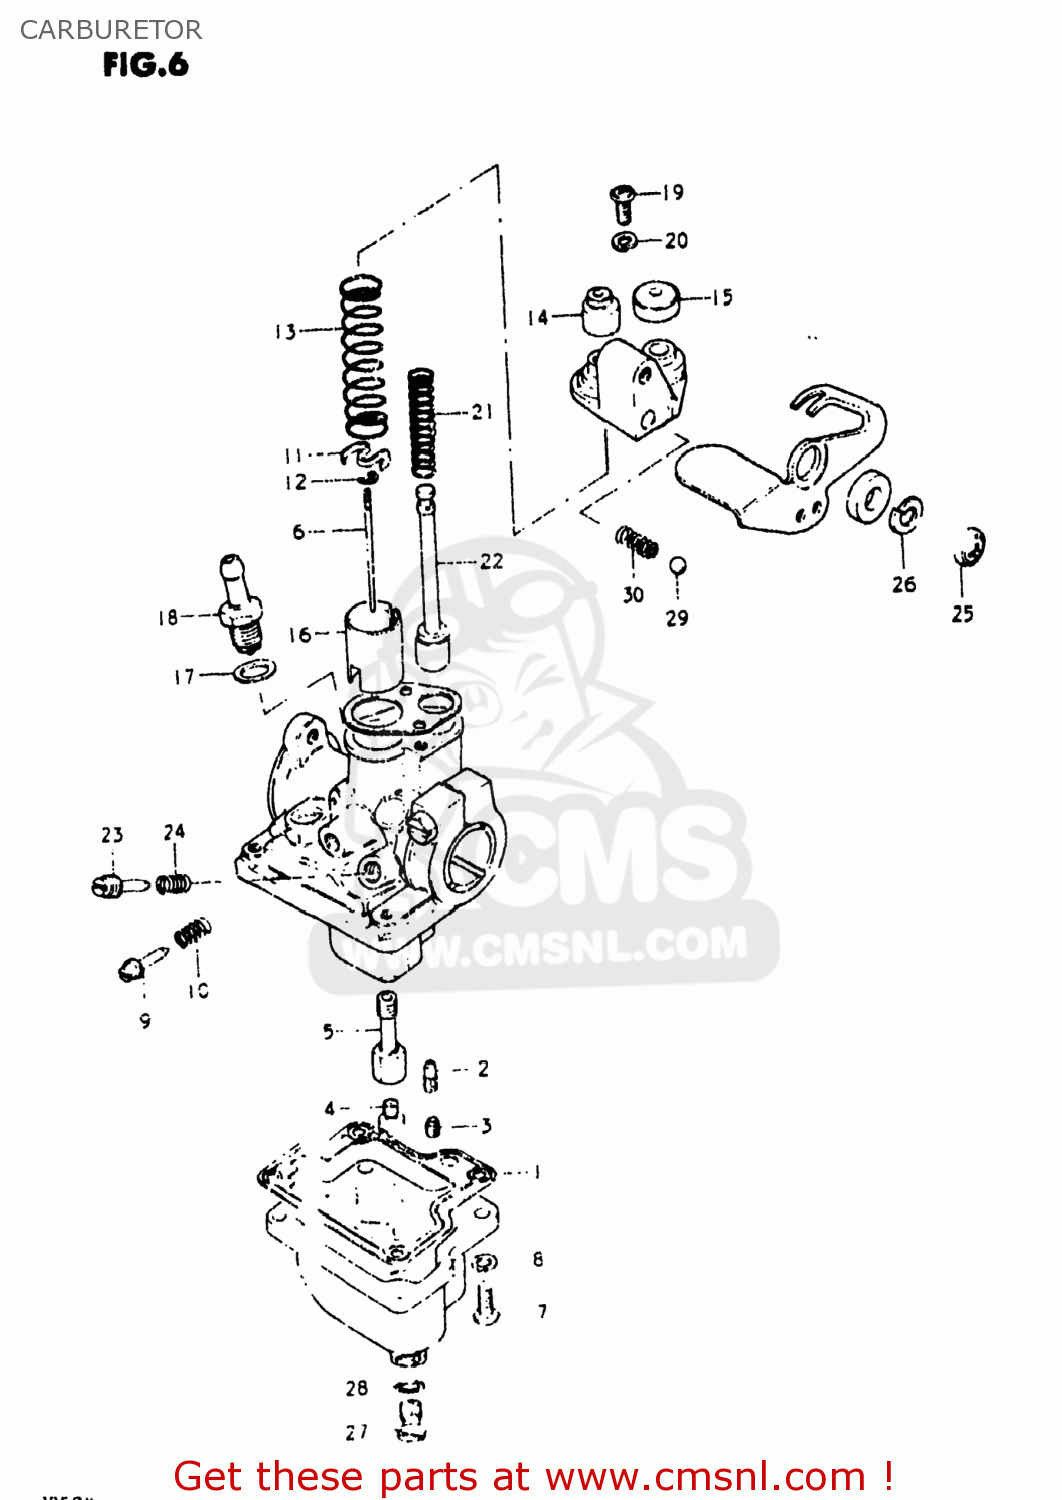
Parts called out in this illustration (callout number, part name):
1	GASKET,FLOAT CAHMBER (NAS)
2	JET,PILOT
3	JET
4	JET,MAIN
5	JET,NEEDLE
6	NEEDLE,JET
7	SCREW
8	LOCK WASHER
9	SCREW,THROTTLE STOP
10	SPRING
11	SEAT,THROTTLE VALVE SPRING
12	CLIP,NEEDLE
13	SPRING,THROTTLE VALVE
14	CAP
15	RUBBER,THROTTLE VALVE CAP
16	VALVE,THROTTLE
17	GASKET (NAS)
18	VALVE ASSY,NEEDLE
19	SCREW 4X10
20	LOCK WASHER
21	SPRING
22	VALVE,STARTER
23	SCREW,AIR
24	SPRING
25	SCREW 6X12
26	LOCK WASHER
27	PLUG
28	GASKET,DRAIN,PLUG (NAS)
29	BALL,STARTER SHAFT
30	SPRING,STARTER SHAFT
